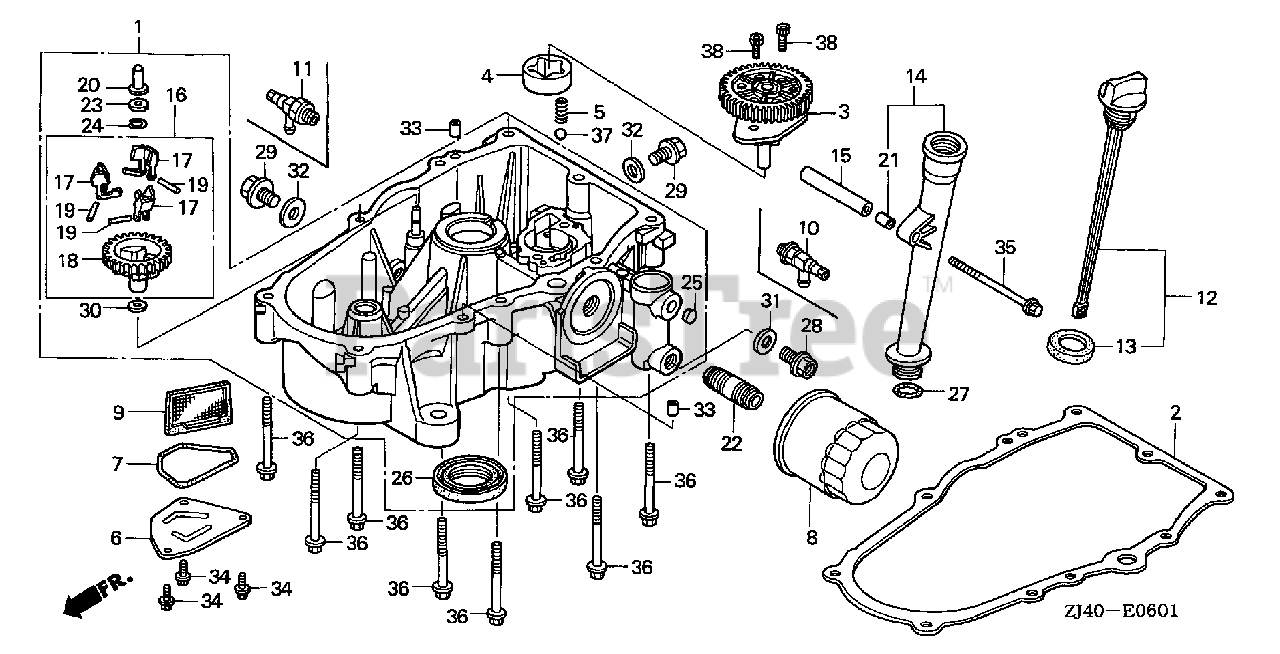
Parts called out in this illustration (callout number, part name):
1	PAN ASSY., OIL
2	GASKET, CASE COVER
3	COVER ASSY., OIL PUMP (TWO BOLTS)
3	COVER ASSY., OIL PUMP (THREE BOLTS)
4	ROTOR, OIL PUMP (OUTER)
5	SPRING, RELIEF VALVE
6	PLATE, OIL FILTER
7	O-RING, OIL PLATE
8	FILTER, OIL (FILTECH TOYO ROKI) (SOLD INDIVIDUALLY)
8	FILTER, OIL (TOYO ROKI) (SOLD INDIVIDUALLY)
9	SCREEN, OIL FILTER
10	VALVE, DRAIN (14X1.5)
11	VALVE, OIL SHUT-OFF
12	CAP ASSY., OIL FILLER
13	GASKET, OIL FILLER CAP
14	EXTENSION, OIL FILLER
15	COLLAR, FILLER SETTING
16	GOVERNOR ASSY.
17	WEIGHT, GOVERNOR
18	HOLDER, GOVERNOR WEIGHT
19	PIN, GOVERNOR WEIGHT
20	SLIDER, GOVERNOR
21	COLLAR, EXTENSION
22	HOLDER, OIL FILTER
23	WASHER (6X16)
24	CLIP, GOVERNOR HOLDER
25	PLUG, SEALING (10MM)
26	OIL SEAL (38X58X9)
27	O-RING (22.1X2.2)
28	BOLT, DRAIN PLUG (14MM)
29	BOLT, DRAIN PLUG (20MM)
30	WASHER, PLAIN (6MM)
31	WASHER, DRAIN PLUG (14MM)
32	WASHER, DRAIN PLUG (20MM)
33	PIN, DOWEL (8X14)
34	BOLT, FLANGE (6X14)
35	BOLT, FLANGE (6X100)
36	BOLT, FLANGE (8X50)
37	BALL, STEEL (#12) (3/8)
38	BOLT, SOCKET (6X16)
